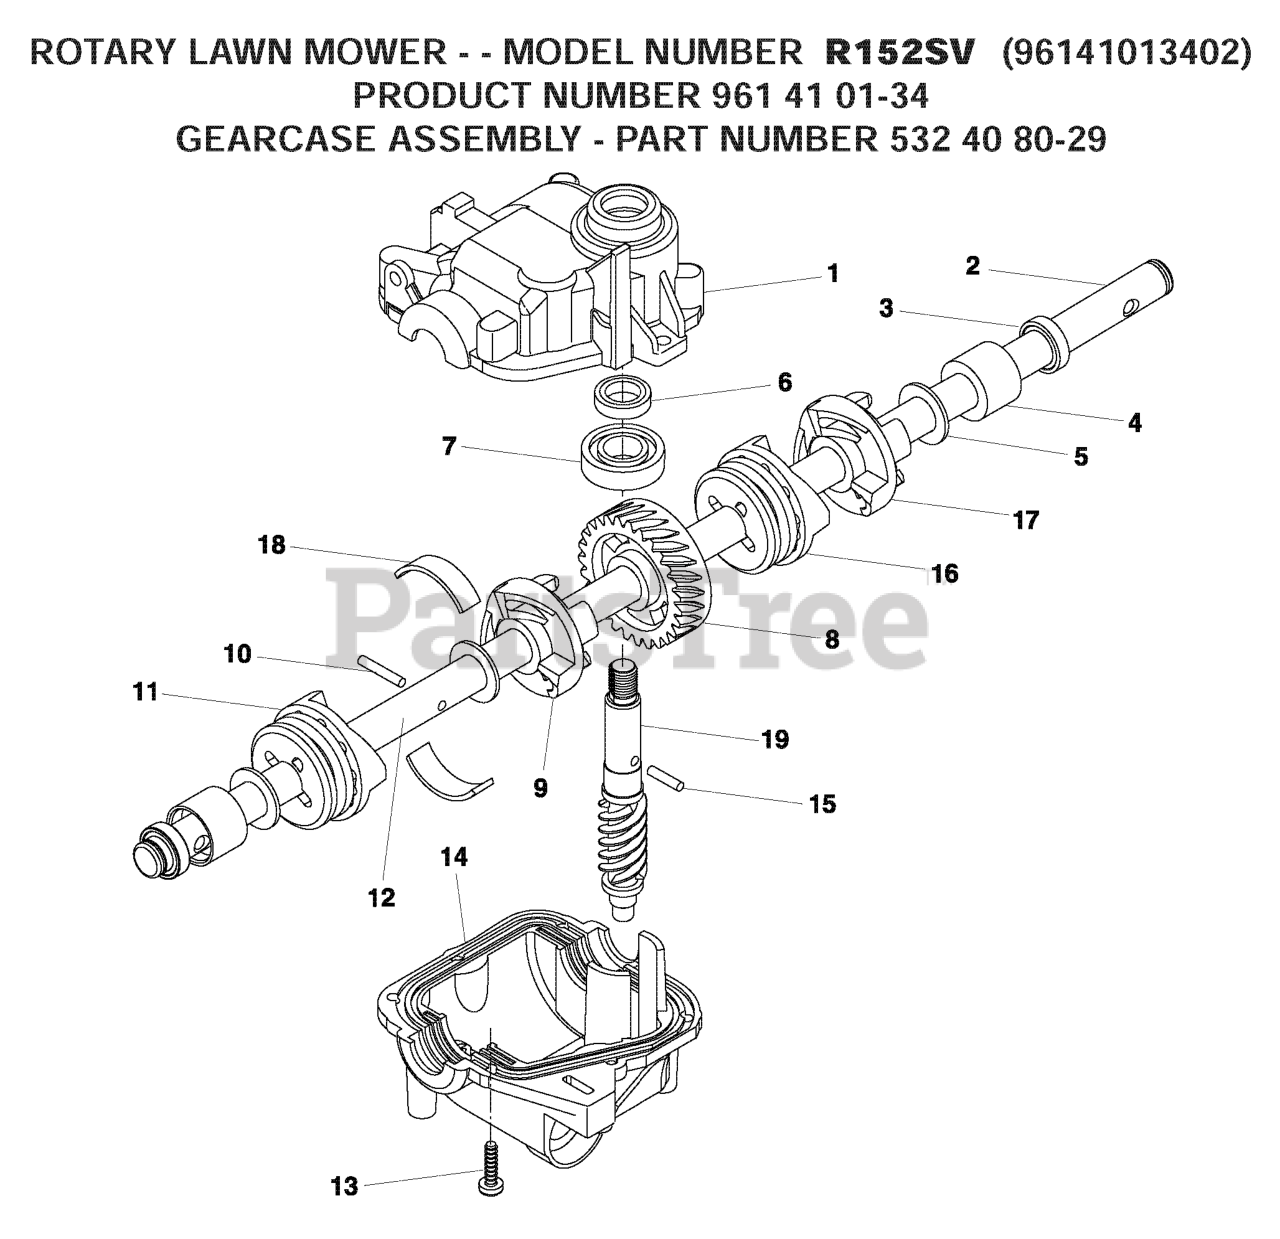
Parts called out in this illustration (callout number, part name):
1	CASE UPPER
3	SEAL.OUTPUT.SHAFT
6	SEAL INPUT SHAFT
8	GEAR 28 TEETH
9	DOG.MOVEABLE.LH.32005
10	PIN 3.50.337 - 33733
11	DOG.FIXED.LH.32003
14	CASE, LOWER
15	PIN 7 33732
16	DOG.MOVEABLE.RH.32006
17	DOG.FIXED.RH.32004
18	SPRING LEAF
